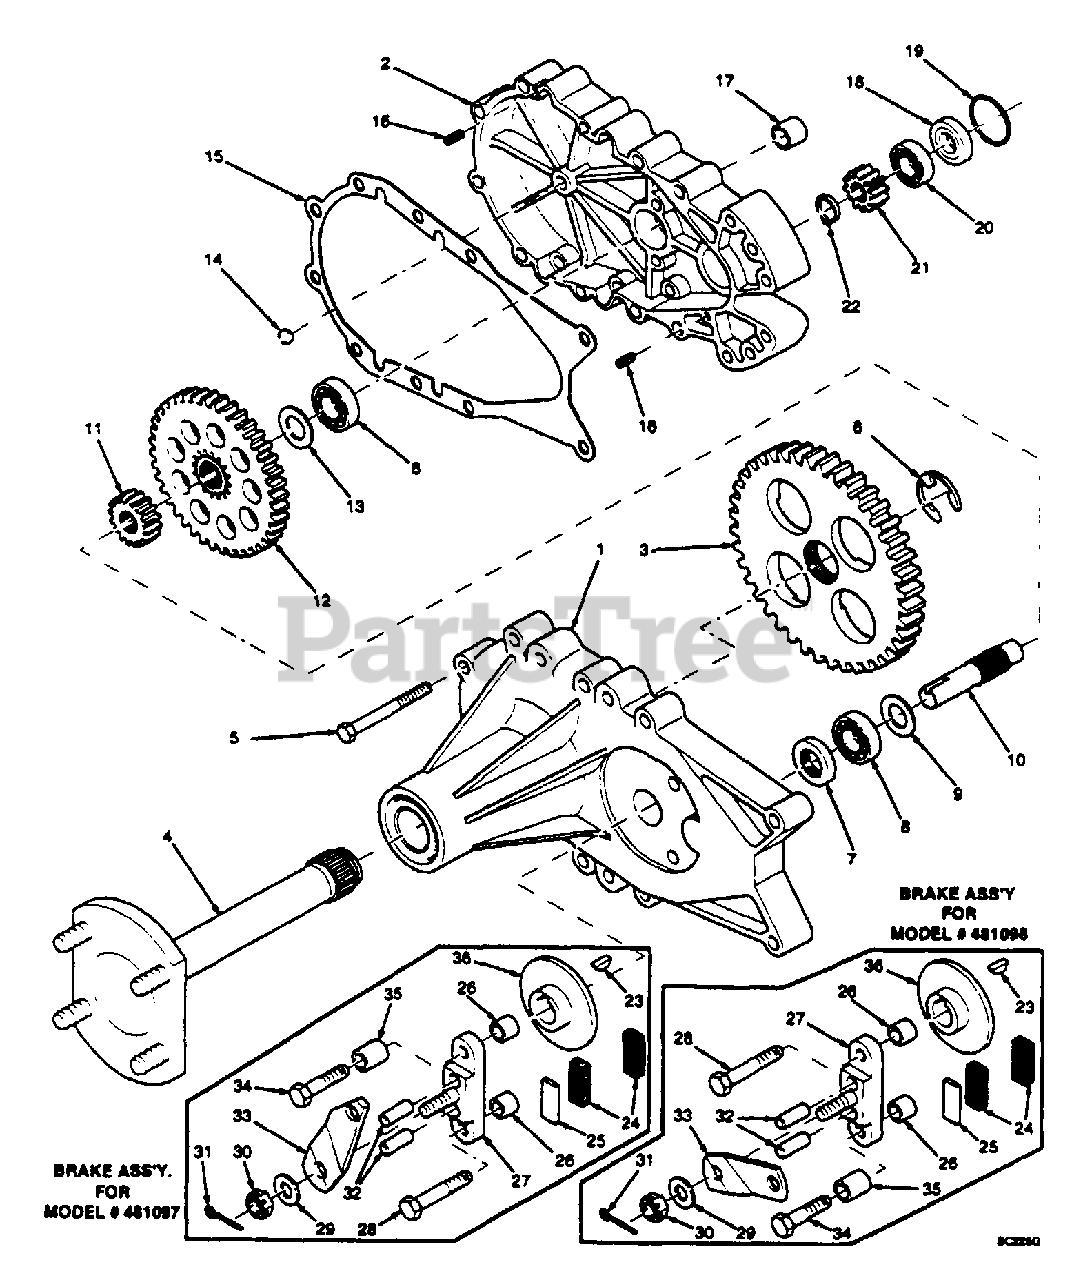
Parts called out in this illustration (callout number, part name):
1	Axle Housing Assembly
2	Hydro Mount Housing
3	Splined 72 Tooth Final Drive Gear
4	Axle Shaft Assembly
5	Bolt, 1/4-20 x 2-1/2 Hex Head
6	E-Ring
7	Oil Seal, 1.25 x .625
8	Ball Bearing, .62ID x 1.38 x.44
9	Washer, HT .62ID x 1.0 OD x.05 Thick
10	Brake Shaft (Splined)
11	Splined Reduction Gear, 17 Tooth
12	Splined 60 Tooth Gear
13	Washer, HT .62ID x 1.0 OD x .05 Thick
14	Ball, 3/8" Diameter
15	Gasket, Housing
16	Pin, Spring 3/10" x 1/2" x 1/2" Long
17	Mounting Spacer
18	Bearing, Spacer
19	O-Ring
20	Ball Bearing 15mm x 35mm x 11mm
21	Input Gear, 11 Tooth
22	Retaining Ring
23	Key, Hi Pro 3/16 x 5/8
24	Puck, Brake
25	Plate, Puck
26	Brake Spacer
27	Brake Yoke Assembly
28	Bolt,1/4-20 x 1-1/2 W/Patch
29	Washer, 7/16 x 7/8 OD x .06 HT
30	Nut, Castle 5/16-24 PL
31	Pin, Cotter
32	Pin, Brake Actuating
33	Arm, Brake Actuator (LH Assy.)
33	Arm, Brake Actuator (RH Assy.)
34	Bolt, 1/4-20 x 2-1O"
35	Spacer, Torsion Spring
36	Disc, Brake
